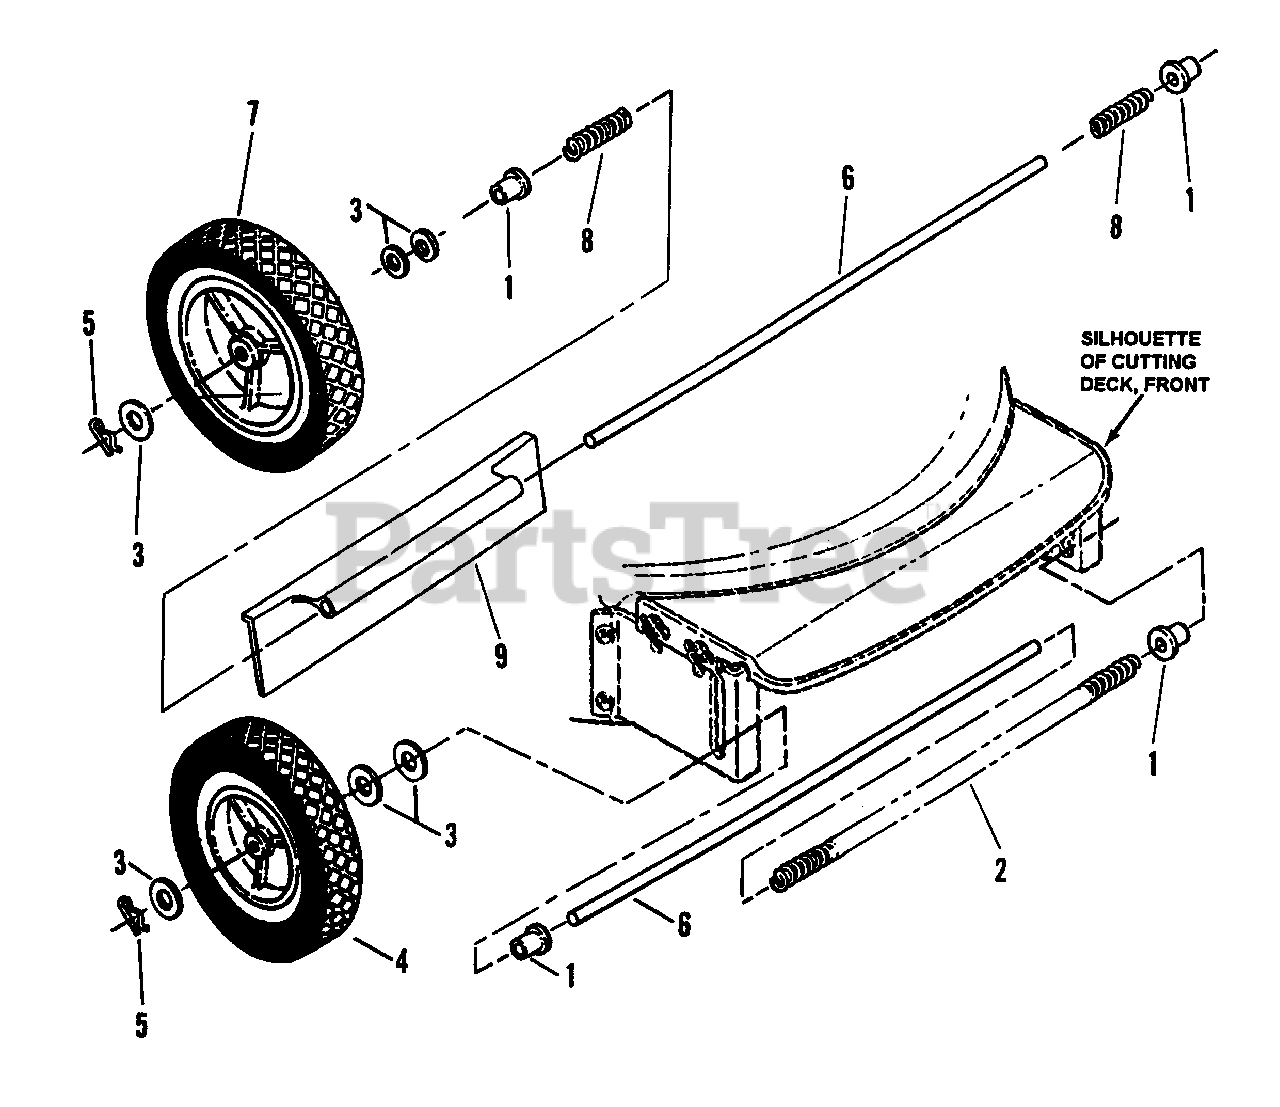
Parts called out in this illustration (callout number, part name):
1	BUSHING, Height Adjustment
2	SPRING, Front Axle
3	WASHER, 3/8" Flat
4	WHEEL, Front 7 x 1.50"
5	HAIRPIN, Cotter
6	AXLE, Front & Rear .375 x 19.60"
7	WHEEL, Rear 8 x 1.75
8	SPRING, Rear Guard
9	GUARD, Rear Foot
